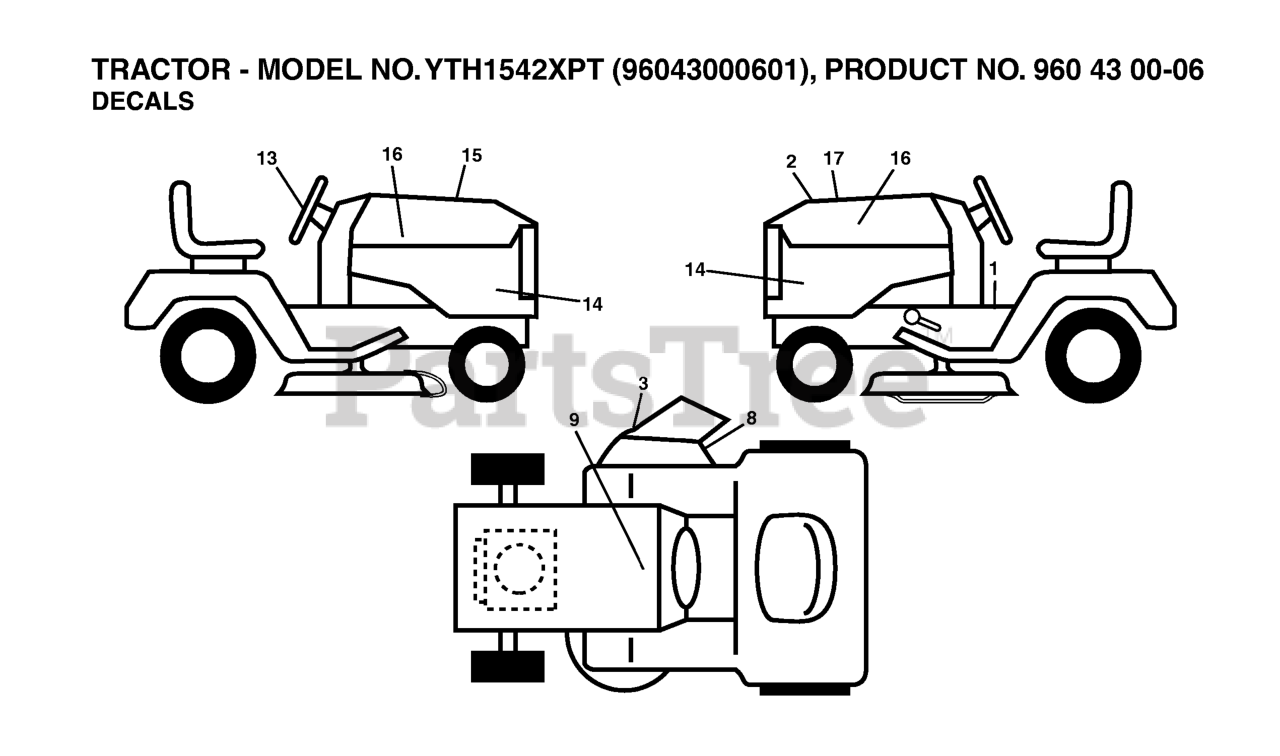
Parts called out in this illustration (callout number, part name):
1	DECAL.FENDER.OPER.TEX.
2	DECAL.HOOD.TOP.INSERT.
3	DECAL.WARN.KEEP.HAND.AWAY
8	DECAL V BELT SCHEMATIC
9	DECAL BTRY SYMBOLS
13	DECAL.WHEEL.STRG.LGN.H
14	DECAL.SDPANEL.YTH1542X
15	DECAL HOOD CUST. RESP.
16	DECAL.HOOD.LOGO.PLAQUE
17	DECAL.RPL.YTH1542XPT.2006
